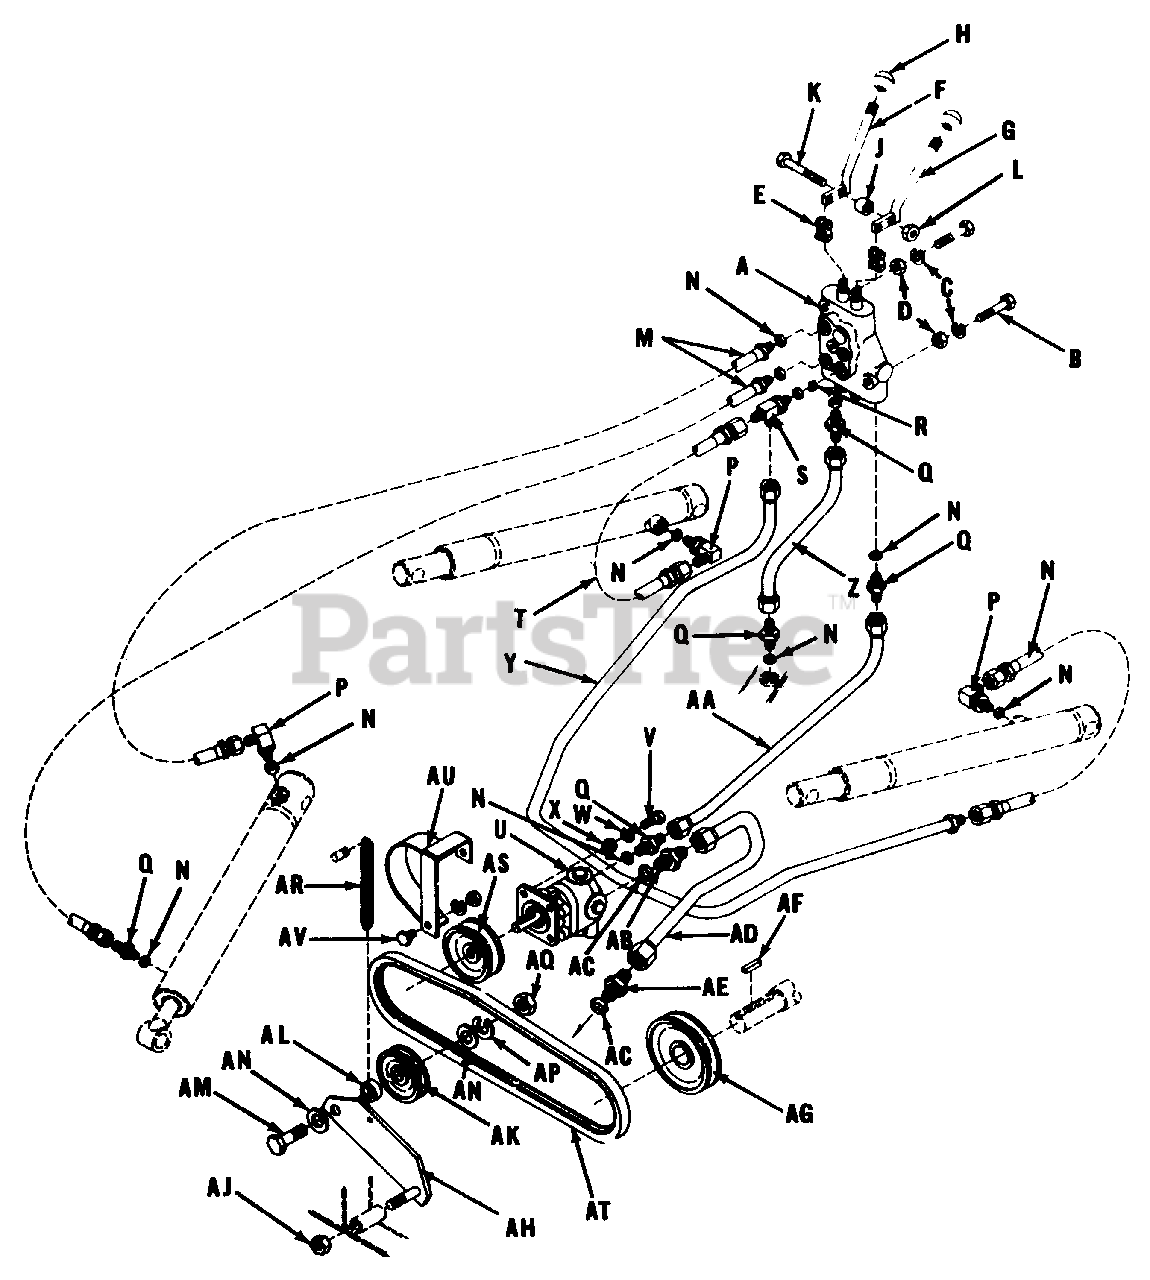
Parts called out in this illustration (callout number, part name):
A	Control Valve Ass'y.
B	Hex. Capscrew, 1/4"-20 N.C.x 2"
C	Lock Washer, 1/4"
D	Full Hex. Nut, 1/4"-20 N.C.
E	Chain Link
F	Bucket Handle
G	Lift Handle
H	Control Handle Knob
K	Hex. Capscrew, 1/4"-28 N.F. x 2-3/4"
L	Full Lock Hex. Nut, 1/4"-28 N.F.
M	Hose Ass'y.
P	90ø Elbow Connector
Q	Straight Connector (6 BC)
R	Orifice Plate Restricter
S	Run Tee Connector (6 BCSTC)
T	Hose Ass'y.
U	Pump Ass'y.-Cessna
V	Hex. Capscrew, 5/16"-18 N.C. x 1"
W	Lock Washer, 5/16"
X	Hex. Full Nut, 5/16"-18 N.C.
Y	Lift Tube Ass'y.
Z	Return Tube Ass'y.
AA	Pressure Tube Ass'y.
AB	Straight Connector (8 BC)
AD	Suction Tube Ass'y.
AE	Filter Connector
AH	Idler Lever Ass'y.
AJ	Full Lock Hex. Nut, 3/8"-24 N.F.
AK	Idler Pulley
AM	Hex. Capscrew, 1/2"-13 N.C. x 2"
AN	Plain Washer, 1/2" Std.
AP	Lock Washer, 1/2"
AQ	Full Hex. Nut, 1/2"-13 N.C.
AR	Tension Spring
AV	Hex. Capscrew, 1/4"-20 N.C. x 1/2"
AW	Lock Washer, 1/4"
AX	Full Hex. Nut, 1/4"-20 N.C.
